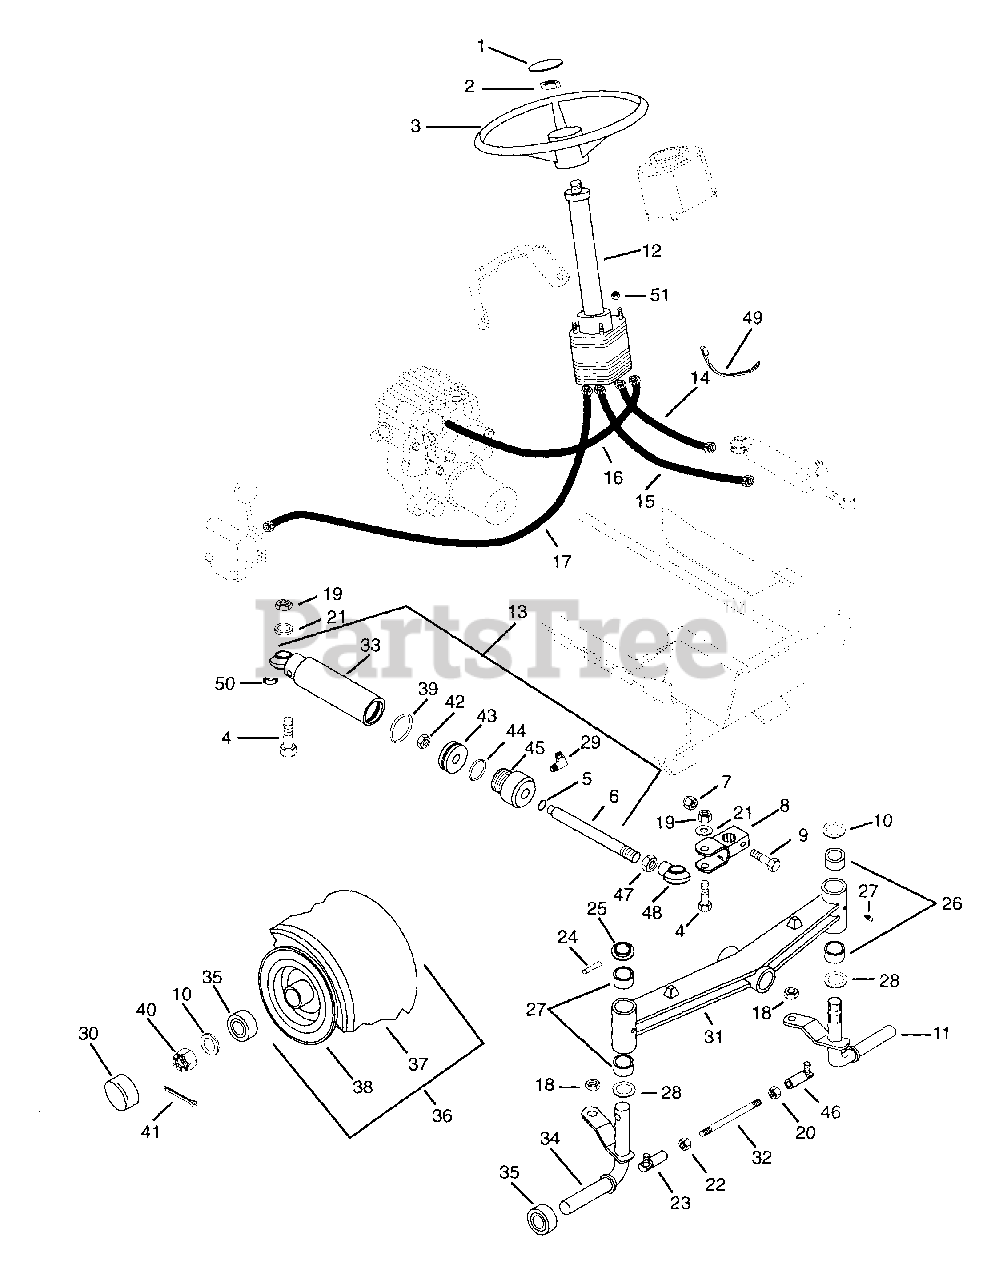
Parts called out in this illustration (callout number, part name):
1	DOME PLUG
2	NUT-LK-JAM .625-18 YWZC
3	STEERING WHEEL
4	BLT-HEX .62-18X2.00 GR5
5	O-RING .609X.609X.139
6	ROD
7	NUT-LK-CROWN .50-13 GR C PL
8	STEERING ARM
9	LOCK BOLT
10	WSHR-FL-STL 1.015X1.500X.125
11	SPINDLE LH
12	STEERING UNIT - HYD.
13	CYLINDER ASSEMBLY (SHORT)
14	HYDRAULIC HOSE 31.5
15	HYDRAULIC HOSE 35.75
16	HOSE - HYDRAULIC 39.75
17	HOSE - HYDRAULIC 48.00
18	NUT-LK .50-20 PL
19	NUT-LK-JAM .625-18 YWZC
20	NUT-JAM .50-20 LH THD PL
21	WSHR-FL-STL .630X1.005X.062 PL
22	NUT-JAM .50-20 PL
23	BALL JOINT R.H.
24	PIN-ROLL .250X1.75
25	SPINDLE CAP
26	BSHG-SLV 1.000X1.125X.875
27	FTG-LUBE .25-28X.256 YWZC
28	PLASTIC WASHER
29	ADAPTER 45 9/16 TO 1/4
30	FRONT HUB CAP
31	FRONT AXLE ASSY
32	TIE ROD
33	CYLINDER
34	SPINDLE RH
35	BRG-BALL 1.0X2.0X.55
36	T/WHL ASSY
37	TIRE 16X6.50-8 2 PLY
39	O-RING 1.625X2.000
40	NUT-SL 1.0-14
41	PIN-COTR .18X1.25 PL
42	NUT-LK .375-24 PL
43	PISTON
44	O-RING 1.937X2.125
45	ROD CAP
46	BALL JOINT L.H.
47	NUT-JAM .625-11 PL
48	BALL END
49	CABLE TIE LG 5-1/2
50	ADAPTER, 90 .25 NPT X .56-18
51	NUT-LK-CTR .312-24 PL
